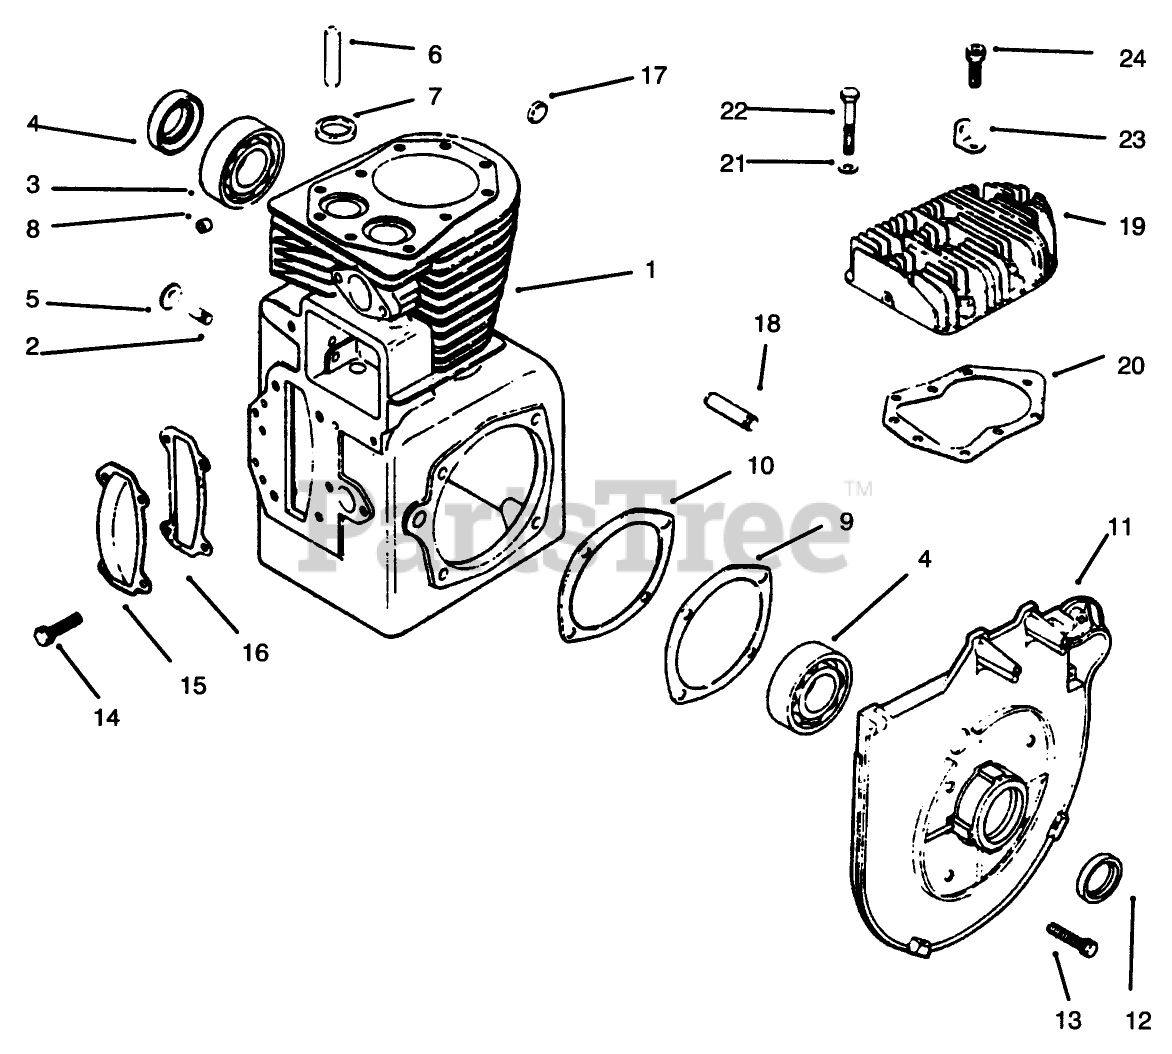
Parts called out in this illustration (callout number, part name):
1	Miniblock W/Out Crank
1	Block-Cylinder 12hp
2	Shaft-Governor Gear
3	Ball Bearing
4	Seal
5	Plug
6	Guide-Valve 12hp
7	Insert
8	Bearing
9	Gasket
10	Gasket
11	Plate-Bearing
12	Seal
13	Screw
14	Screw
15	Cover
16	Gasket
18	Shaft
19	Head-Cylinder
20	Gasket
21	Washer
22	Screw
23	Strap-Lifting
24	Screw
